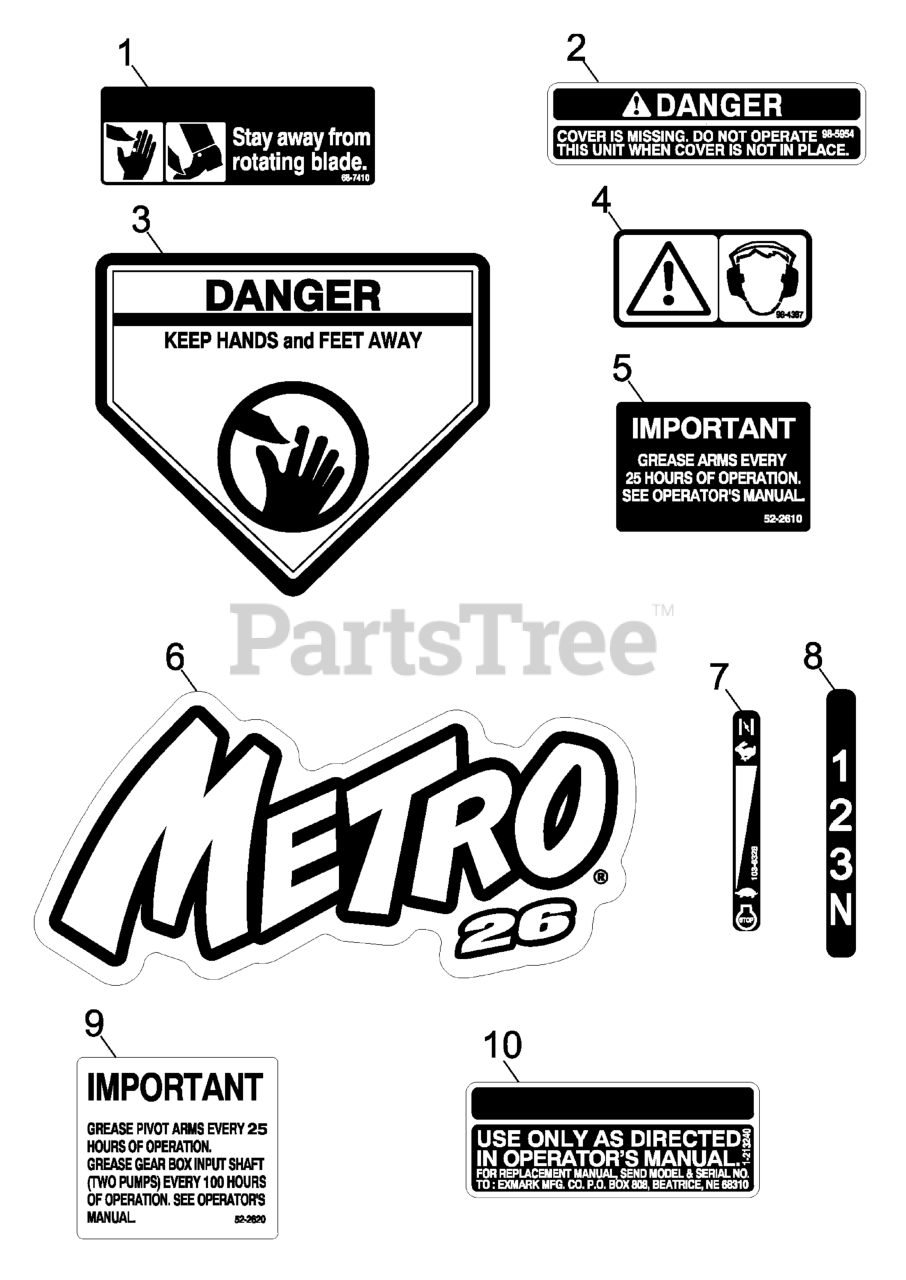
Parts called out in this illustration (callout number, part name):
1	DECAL-BLADE
2	DECAL-COVER, MISSING
3	DECAL-DANGER
4	DECAL-PROTECTION, EAR
5	LABEL-GREASE, HP
6	DECAL,METRO 26
7	DECAL-THROTTLE / CHOKE
8	DECAL,SHIFTER
9	Decal, Grease
